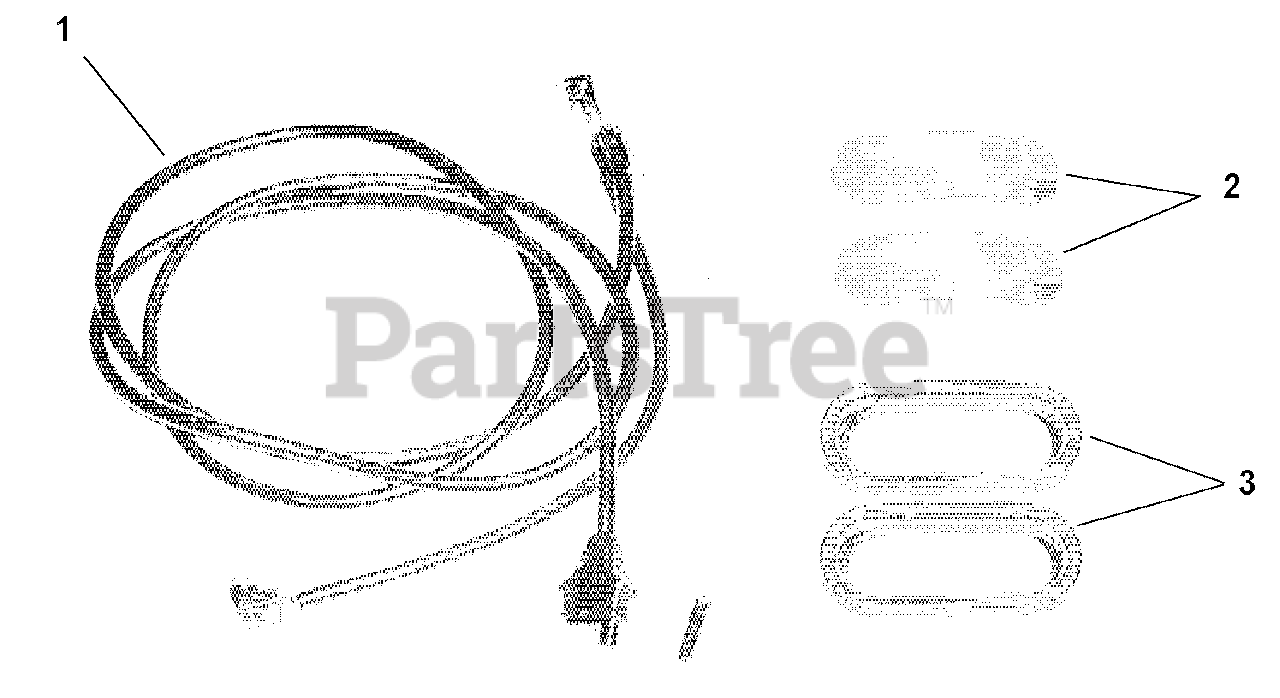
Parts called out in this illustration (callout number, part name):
1	WIRE HRNS,TRAILER LIGHT KIT
2	TAIL LIGHT HOUSING W/ BULB
3	GROMMET, TAIL LIGHT MOUNTING
